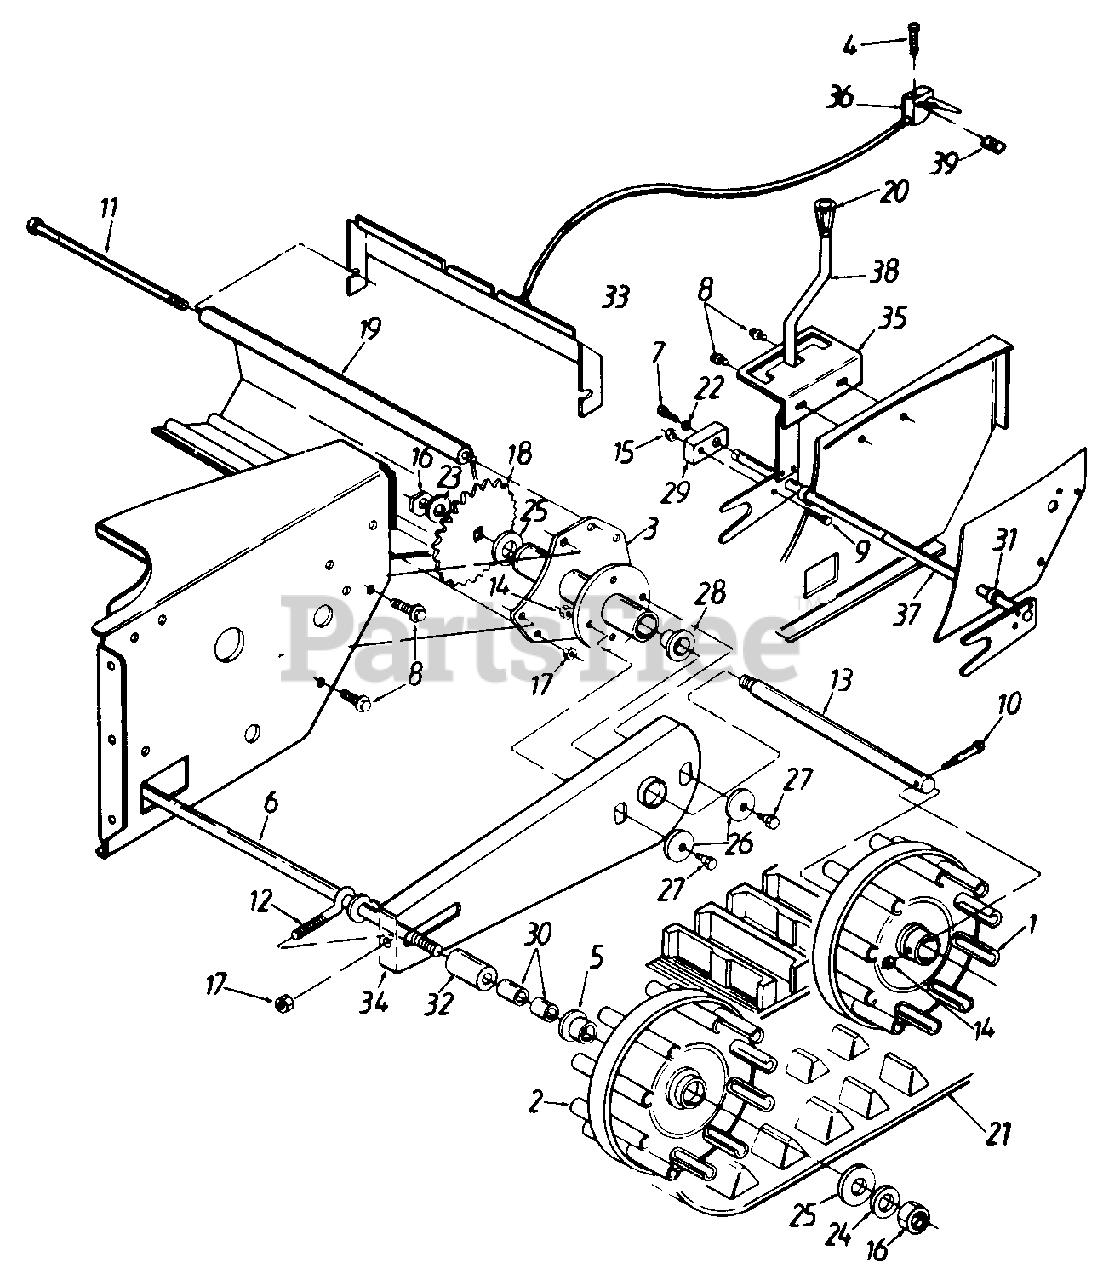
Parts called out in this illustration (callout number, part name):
1	Drive Wheel Ass'y.
2	Idler Wheel Ass'y.
4	Oval C-Sunk Hd. Scr. 10-24 x 1.375" Lg.
5	Flange Bearing 3/4" I.D. x 15/16" Lg.
7	Hex Bolt 5/16-24 x .75" Lg.
8	Hex Wash. TT-Tap Scr. 5/16-18 x .62" Lg.
9	Hex Bolt 3/8-24 x 1.5" Lg. (Special)
10	Bolt 5/16-18 x 1.5" Lg.
11	Hex Bolt Ass'y. 5/16-18 x 9.81" Lg.
12	Eyebolt 5/16-18 x 3" Lg.
13	Drive Axle
14	Hex Cent. L-Nut 5/16-18 Thd.
15	Hex Cent. L-Nut 3/8-24 Thd.
16	Hex Ins. Jam L-Nut 1/2-20 Thd.
17	Hex L-Nut 5/16-18 Thd.
18	24 Tooth Sprocket
19	Track Housing
21	Snow Track
22	L-Wash. 5/16" I.D.
23	Bell-Wash. .515" I.D. x 1.14" O.D.
24	Fl-Wash. .531" I.D. x 1.25" O.D.
25	Fl-Wash. .793" I.D. x 1.24" O.D.
26	Fl-Wash. 3/8" I.D. x 7/16" O.D.
27	Shld. Bolt .437" Dia. x .162
28	Flange Bearing 3/4" I.D. x 15/16" Lg.
29	Lift Shaft Drive
30	Spacer .5" I.D. x .78" Lg.
31	Spacer .628" I.D. x .5" Lg.
32	Spacer .51" I.D. x 1.34" Lg.
36	Track Steer Cable w/Trigger
39	Flat Weld Nut #10-24 Thd.
